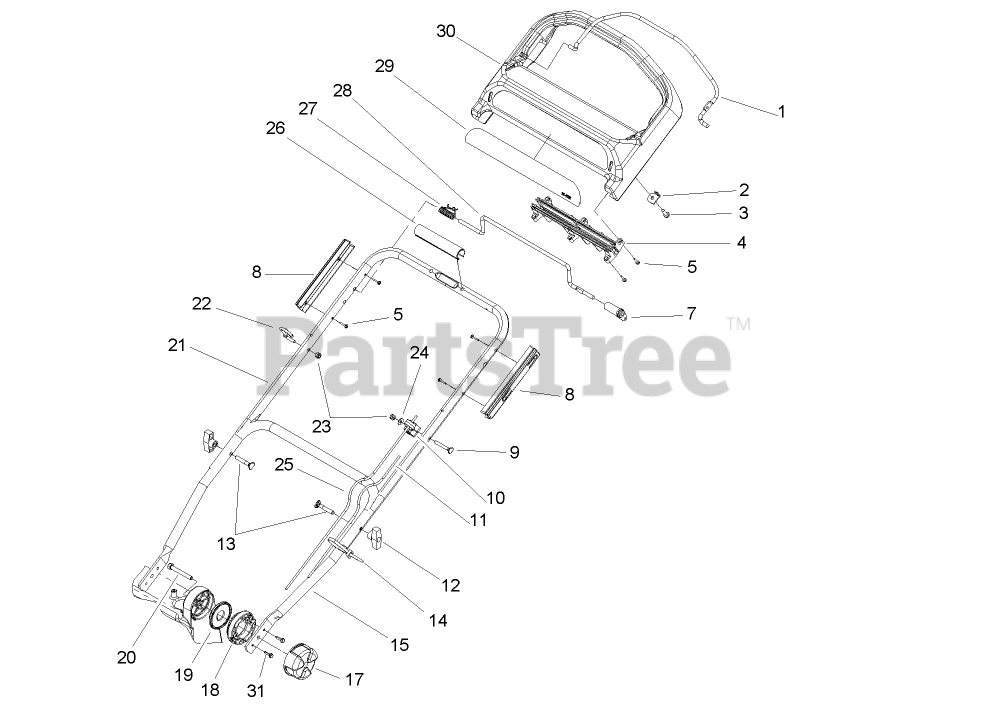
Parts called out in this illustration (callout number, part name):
1	BAIL-BRAKE
2	RETAINER-CABLE
3	SCREW-HWH
4	RETAINER-CONTROL ROD, TRACTION
5	SCREW-PPH
7	LEVER-TRACTION
8	GUIDE-HANDLE, CONTROL
9	SCREW
11	CABLE-TRACTION
12	KNOB-HANDLE
13	SCREW-HANDLE
14	TIE-CABLE
15	HANDLE-LOWER
17	KNOB-ADJUSTING, HANDLE
18	DISK-ADJUSTING, HANDLE
19	DISK-HOLDING, HANDLE
20	CAPSCREW
21	HANDLE-UPPER
22	GUIDE-ROPE
23	NUT-LOCK, NI
24	WASHER-FLAT
25	CABLE-BRAKE
26	COVER-HANDLE
27	SPRING-TORSION, RH
29	DECAL-PANEL
30	HANDLE-CONTROL
31	SCREW-HWH
